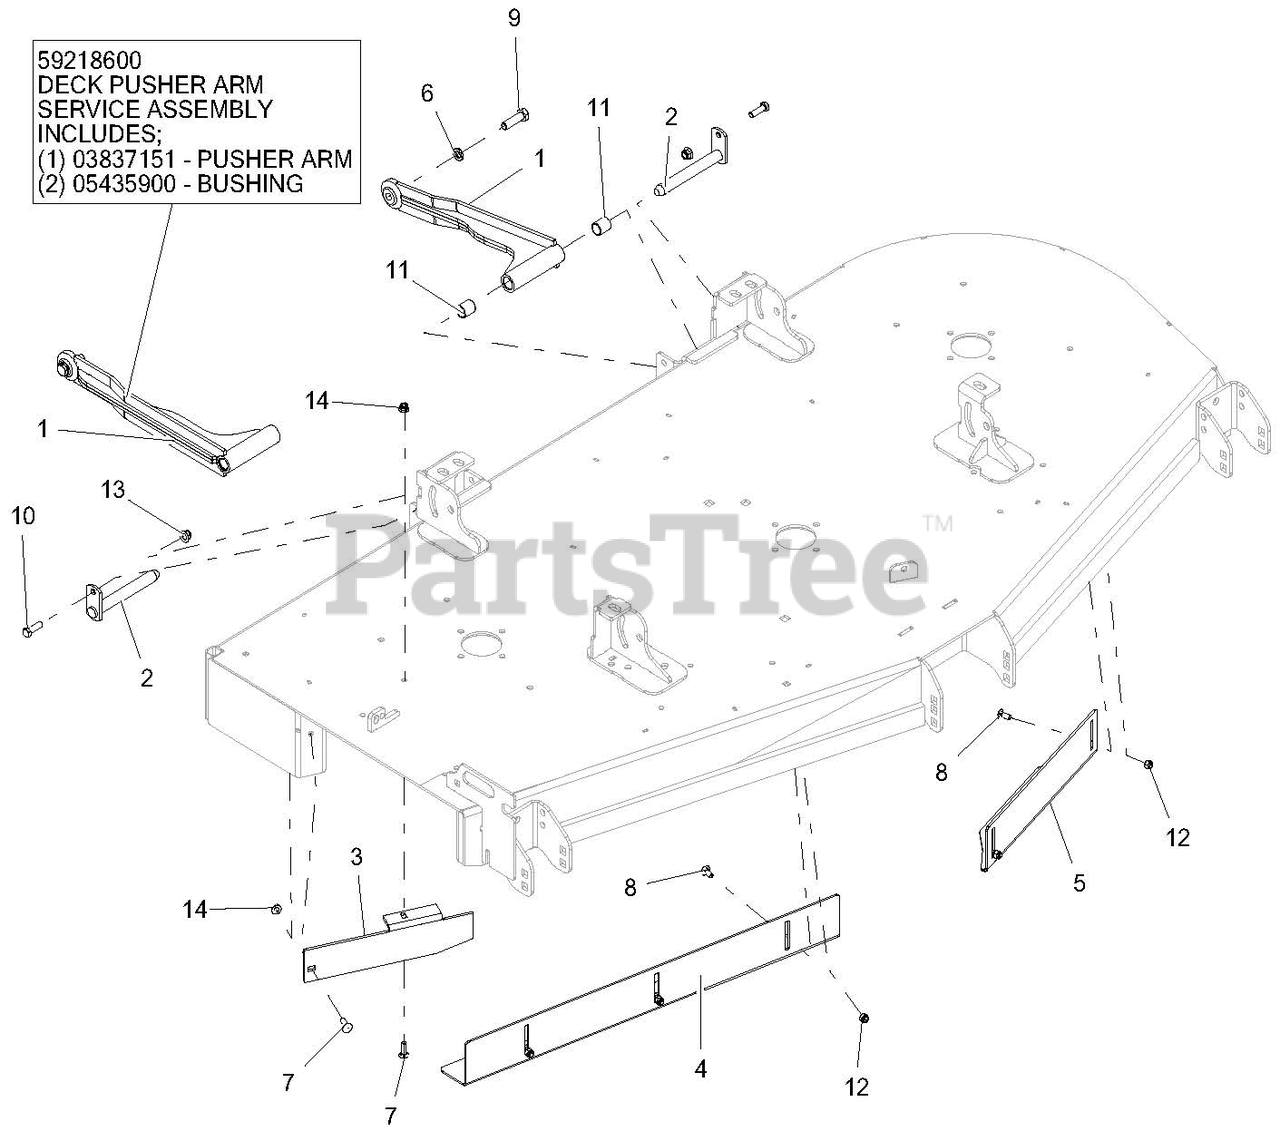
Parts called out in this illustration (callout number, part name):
1	WMT, DECK STABILIZER ARM-BLACK
1	DECK PUSHER ARM SERVICE ASSEMBLY
1	PUSHER ARM
1	BUSHING
2	WLDMT, MOWER MTG. PIN
3	BAFFLE, 72" DISCHARGE-RED
4	BAFFLE, 72" RH VACUUM-BLACK
5	BAFFLE, 72" LH VACUUM-BLACK
6	WSHR-LK .50X.125 REG YWZC
7	BLT-RDHDSQSHNK .31-18X1.00 G5 Y
8	BLT-RDHDSQNK .31-18X.75 G5 YWZC
9	BLT-HEX .50-13X1.75 GR5 YWZC EP80
10	BLT-HEX .38-16X1.25 GR5 YWZC
11	BRG, .750 X .875 X 1.000
12	NUT-LK-NYL .312-18 YWZC
13	NUT-LK-NYL-FLG .38-16 YWZC
14	NUT-LK-NYL-FLG .31-18 YWZC
